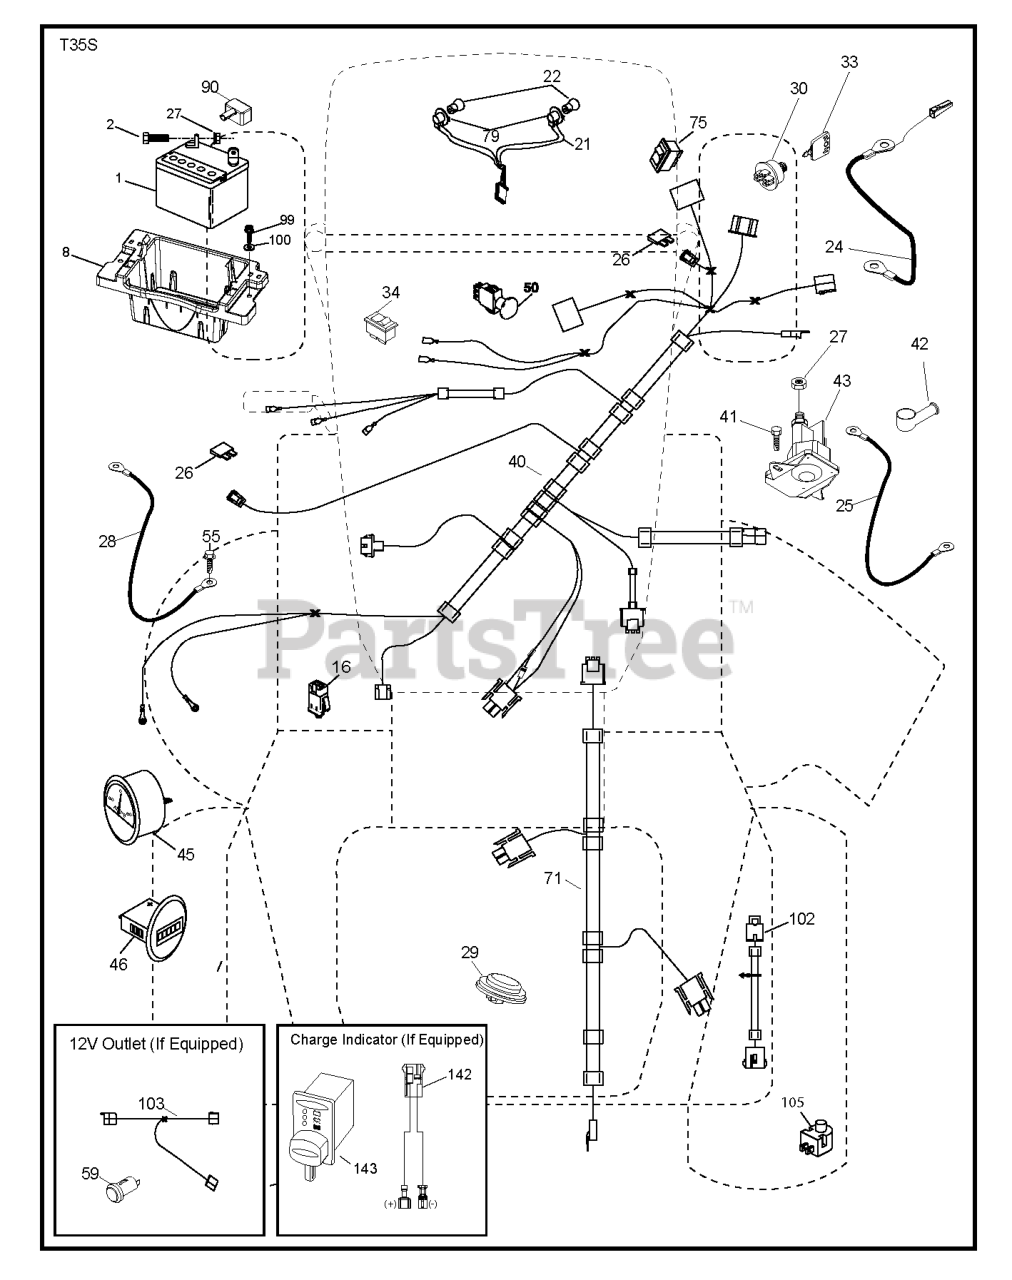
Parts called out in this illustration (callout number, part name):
1	Battery, Dry 30 Amp
2	BOLT.HEX.1/4.X.3/4.DICHROMATE
8	TRAY.BATTERY BOX.FRONT
16	SWITCH INTERLOOK PUSH-IN
21	HARNESS.LIGHT W/4152J BULBS
24	CABLE.FRBATT.W/WIRE.8GA.8
25	CABLE.STARTER.8GA.17.5
26	FUSE 20AMP
27	NUT
28	CABLE.GROUND.21"BLK.8GA.90T
29	SWITCH.SEAT.DELTA.OPC.
30	SWITCH.IGN.DELTA.W.LGH.ROS
33	KEY.CHAIN.BLISTER.PACK.GEN.INT
40	HARNESS.DASH.EDIFF.RND.CHR.EF
41	SCREW
42	TERMINAL COVER
43	SOLENOID.W/BRASS.PLUNGER
45	GAUGE.AMMETER.SILVER/WHITE
46	GAUGE.HOUR.METER.SILVER/WHITE
50	RP.SWTICH.PTO.8.TERMINAL
55	SCREW 5/16"
59	OUTLET.12-VOLT
71	HARNESS.IGN.CHASSIS.TEX.DCKLOC
75	SWITCH.ON/OFF.(DIFF.LOCK)
79	BULB HOLDER ASM.
90	COVER.TERMINAL.BATTERY
99	SCREW HEXWSHR 1/4-20X3/4
100	WASHER
102	HARNESS PIGTAIL PCH TEX ROS
103	HARNESS.PIGTAIL.12V.OUTLET.
105	REVERSE SWITCH
142	CHARGE.PORT.PIGTAIL HARNESS
143	CHARGE.PORT
